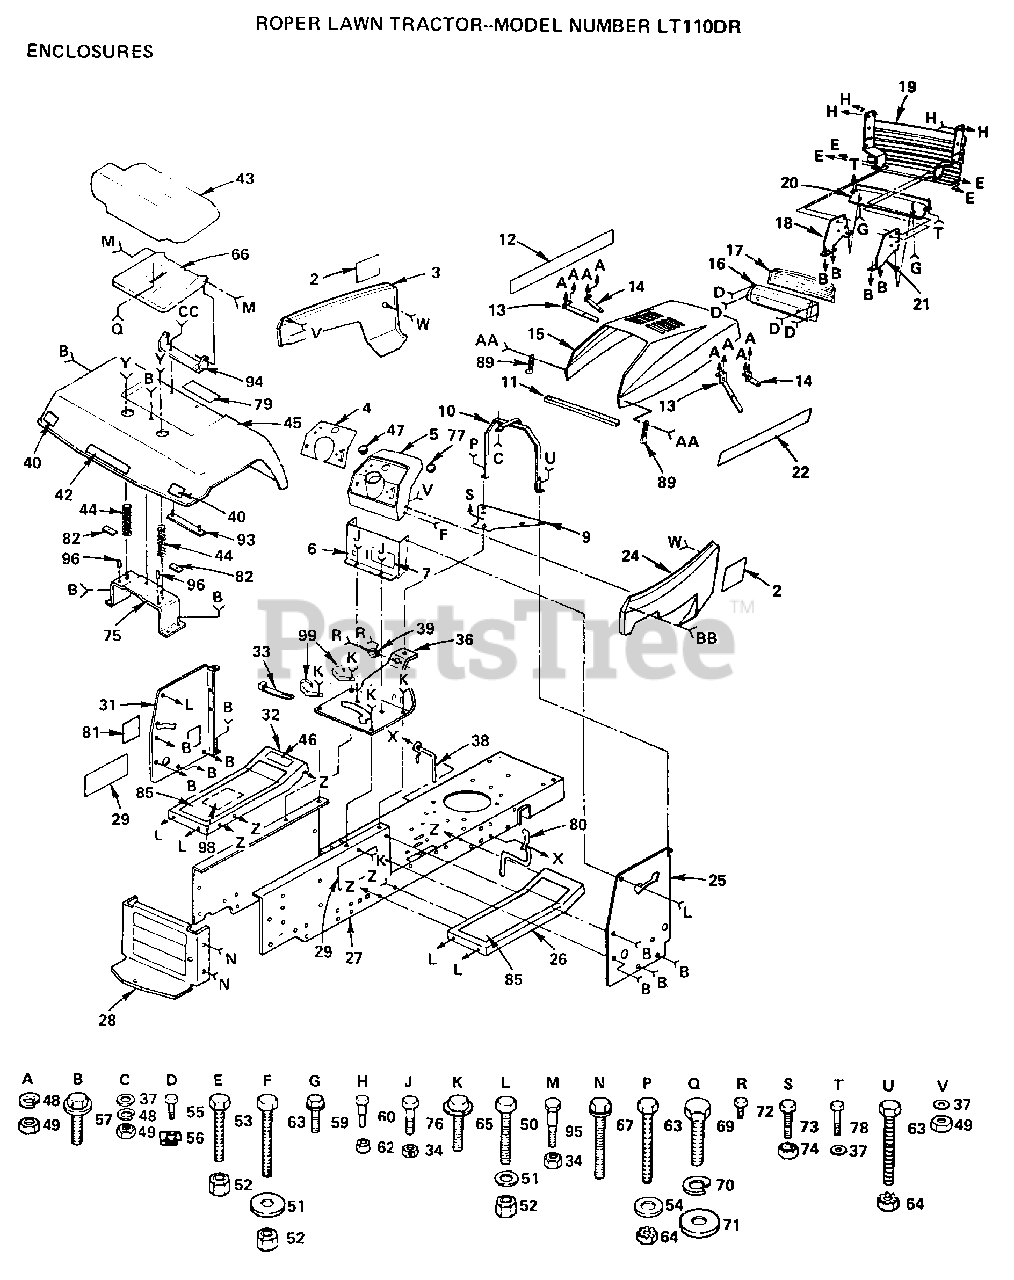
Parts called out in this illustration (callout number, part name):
5	DASHBOARD LT
6	DASH ASSY LT
10	SUPPORT ASSY LT
11	FOAM-STRIP LT
17	LENS LT
18	SUPPORT-GRILL LT
25	PANEL DASH RH YT
31	PANEL DASH HYT
33	WIRE TIE
37	WASHER PM
40	REFLECTOR-TAIL YT
47	PLUG-DASH T
51	WASHER
53	BOLT
54	WASHER
56	"""J"" FASTENER LT"
57	SCREW
59	SCREW
60	BOLT T
64	NUT
65	SCREW LT
67	SCREW
69	BOLT
71	WASHER
73	BOLT
77	PLUG BUTTON T
78	SCREW HEX CRT
82	"CLAMP, SPRING LT"
85	PAD FOOTREST T
96	NUT-PUSH YT
99	CLIP T
